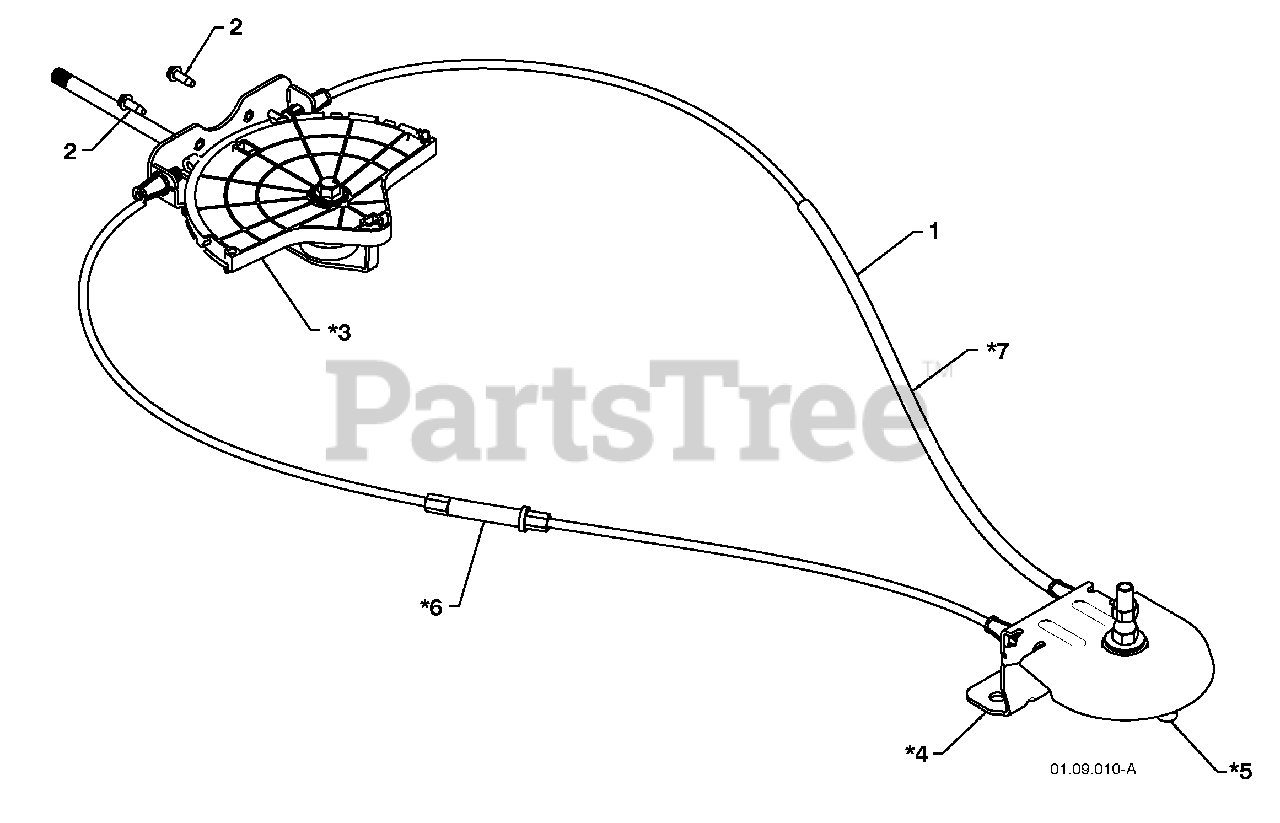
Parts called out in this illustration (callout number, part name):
1	LEVER/CABLE ROTATOR ASSEMBLY
2	SCREW 10-24 X .625
3	ROTATOR HEAD
4	ROTATOR PIVOT BRACKET
5	PULLEY PIVOT
6	CABLE ASSEMBLY ADJUSTABLE
7	CABLE ASSEMBLY HEAT SHIELD
